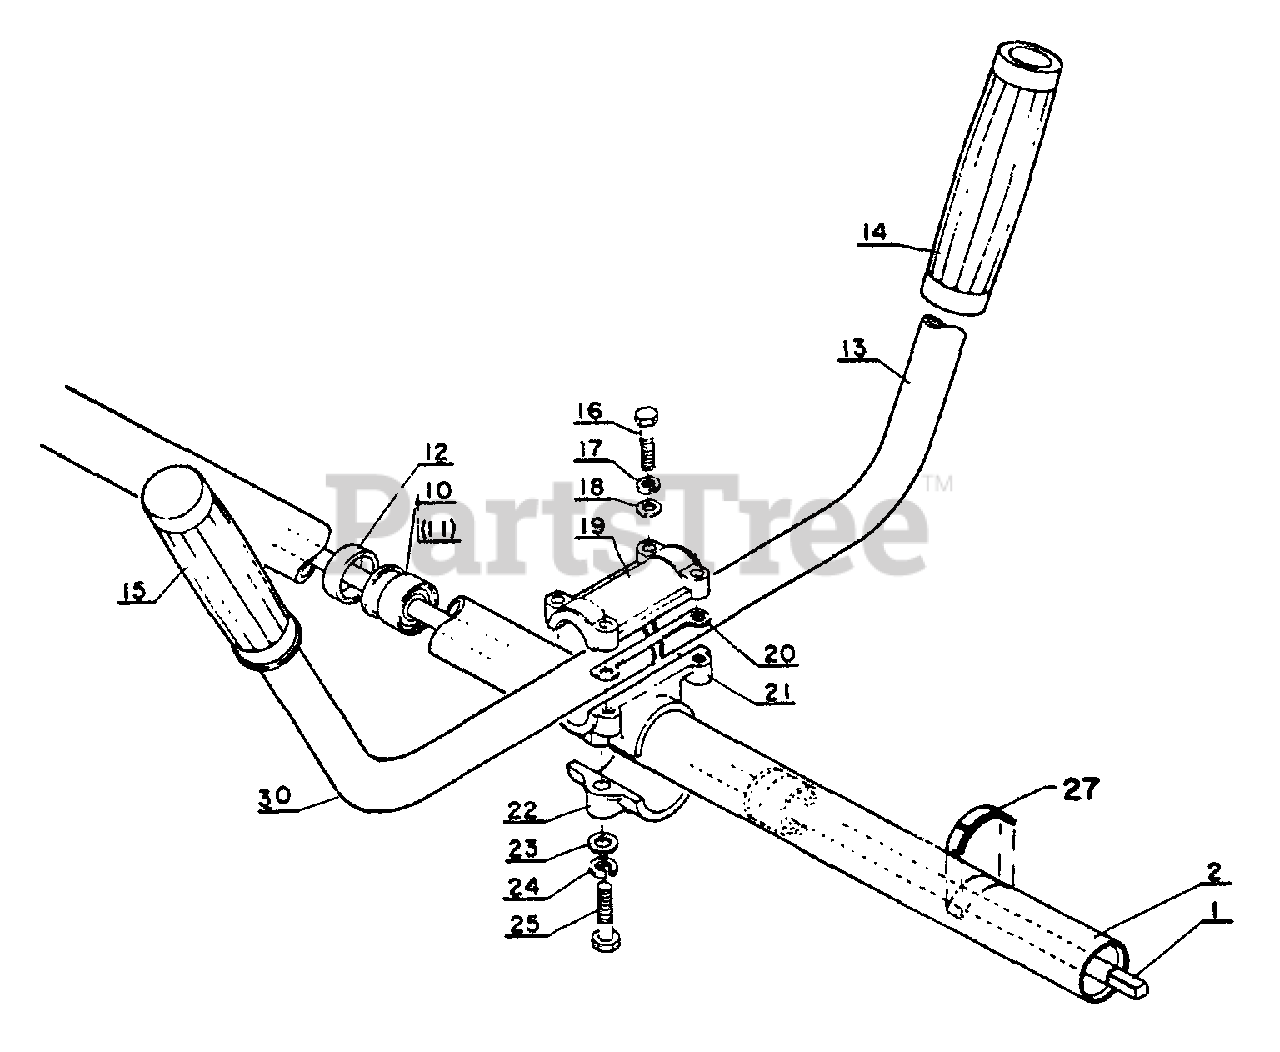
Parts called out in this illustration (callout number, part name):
1	DRIVESHAFT
2	PIPE, MAIN
13	HANDLE
14	GRIP, HANDLE
15	GRIP, HANDLE
16	BOLT - 5×25
17	WASHER, SPRING 5
18	WASHER, FLAT 5.5×10×0.8
19	BRACKET ASSY, HANDLE
21	BRACKET ASSY, HANDLE
22	BRACKET ASSY, HANDLE
23	WASHER 6.5×11.5×0.8
24	WASHER, SPRING 6
25	BOLT - 6×30
27	LABEL - ALIGNMENT
30	HANDLE, LEFT
